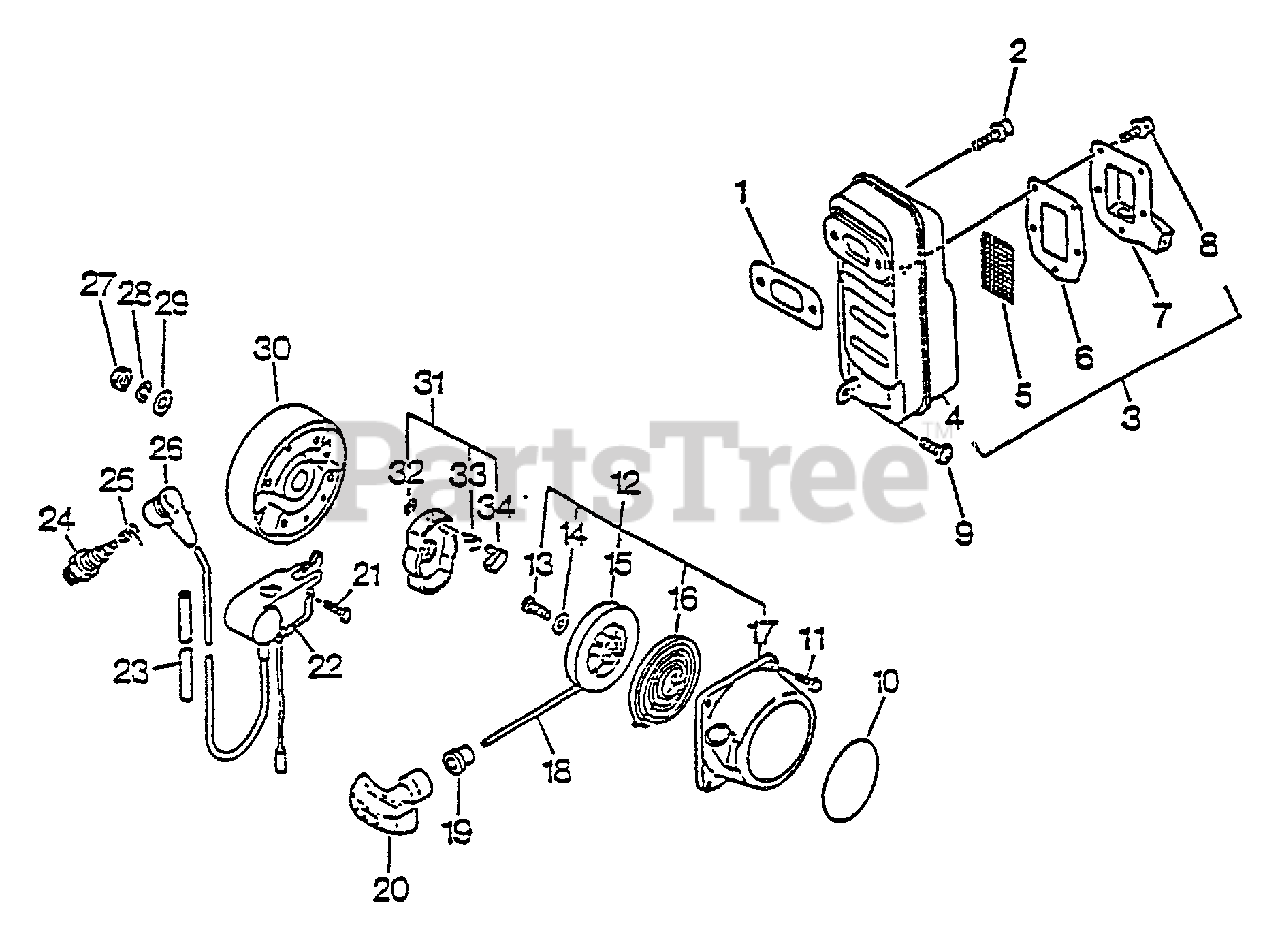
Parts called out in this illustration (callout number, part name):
1	GASKET, EXHAUST
2	BOLT 6×20
3	MUFFLER ASSY
4	MUFFLER
5	SCREEN, SPARK ARRESTER
6	GASKET, EXHAUST
7	ADAPTER
8	SCREW 4×10
9	BOLT 5×20
11	SCREW 4×18
12	STARTER ASSY
14	WASHER
15	REEL, ROPE
16	SPRING, RECOIL
17	CASE, RECOIL STARTER
18	ROPE, STARTER 3.8×1400
19	GUIDE, ROPE
20	GRIP, STARTER
21	BOLT 5×20
22	COIL, IGNITION
23	TUBE, VINYL 6.3×8×380
24	SPARK PLUG - BPM7A
25	TERMINAL, SPARK PLUG
26	CAP, SPARK PLUG
28	WASHER, SPRING 10
29	WASHER, SPRING 10
30	FLYWHEEL
31	PAWL ASSY, STARTER
32	E-RING 4
33	SPRING, RETURN
34	PAWL, STARTER
